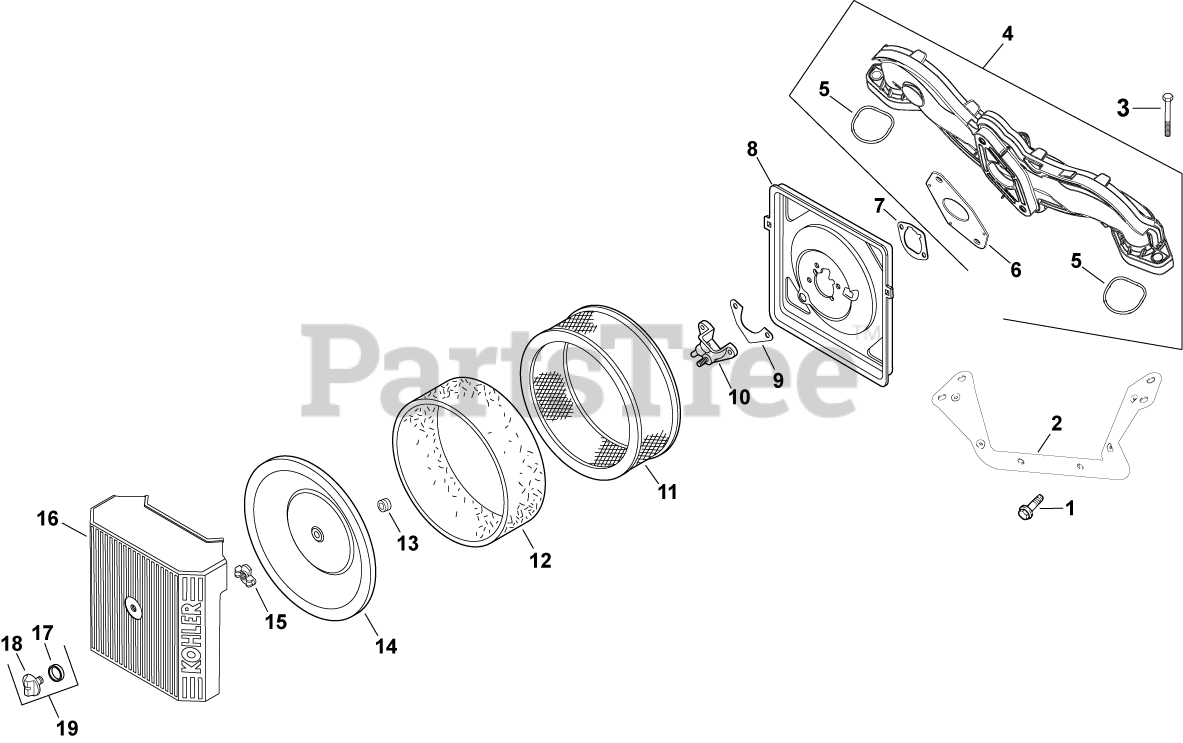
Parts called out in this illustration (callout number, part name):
1	SCREW, FLG THD FRM M5X.8X10
2	BRACKET, AIR CLEANER BASE
3	SCREW, FLG M6X1.0X40
4	KIT, INTAKE MANIFOLD USE 24 164 266-S
5	O-RING, INTAKE PORT
6	GASKET, CARBURETOR
7	GASKET, AIR CLEANER BASE
8	BASE, AIR CLEANER-USE 24 094 82-S
9	GASKET, FUEL SPITBACK CUP
10	CUP, FUEL SPITBACK W/O NIPPLE
11	ELEMENT, AIR FILTER (HIGH) - Also available Retail Packaged 24 883 03-S1 Air Filter Kit
12	PRE-CLEANER (HIGH)
13	SEAL, BREATHER
14	COVER, INNER AIR CLEANER
15	NUT, WING
16	COVER, AIR CLEANER
18	KNOB, COVER
19	KIT, KNOB W/SEAL
